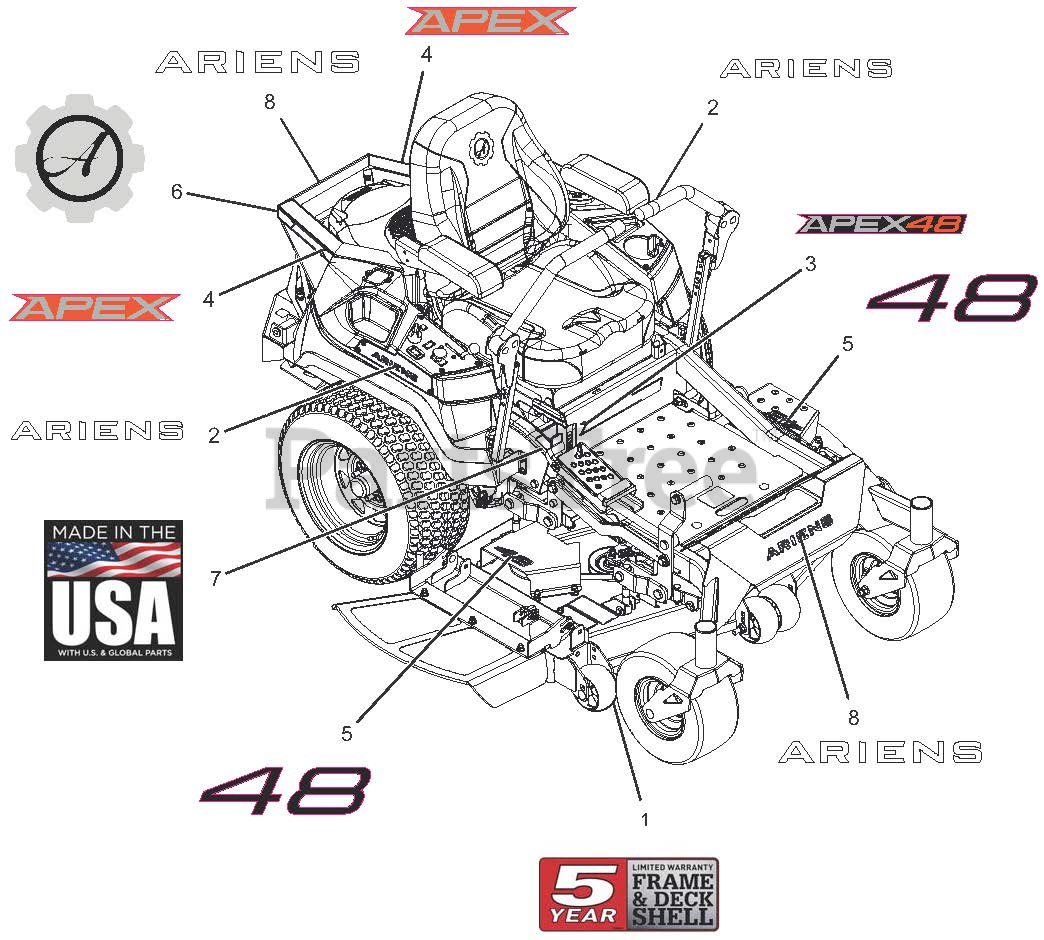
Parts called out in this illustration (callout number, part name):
1	DECAL-ARIENS, DECK 5 YEAR
2	DECAL, ARIENS (6.50")
3	DECAL, 48" APEX KICKPLATE
4	DECAL, APEX FENDER
5	DECAL, BLACK 48
6	DECAL, ARIENS-GEAR BADGE -THK
7	DECAL, MADE IN USA
8	DECAL - ARIENS 9.625"
9	DECAL, DASH DECAL
